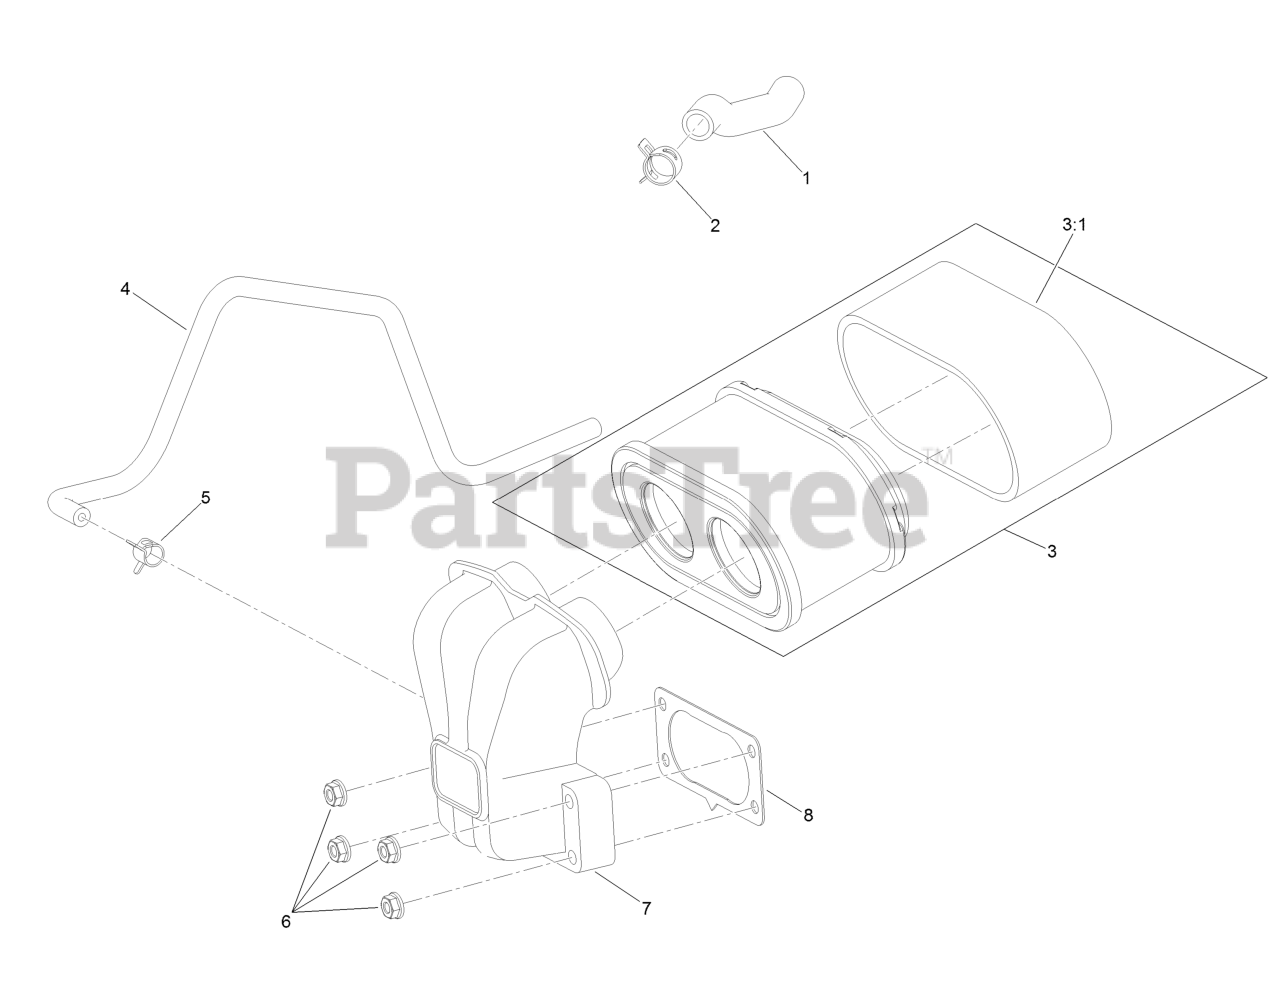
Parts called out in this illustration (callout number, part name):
1	Tube-Breather
2	Clamp-Hose
3	Filter-Air, Complete
3:1	Filter-Pre, Foam
4	Hose-Fuel
5	Clamp-Hose
6	Nut-Flange
7	Manifold-Filter, Air
8	Gasket-Carburetor
